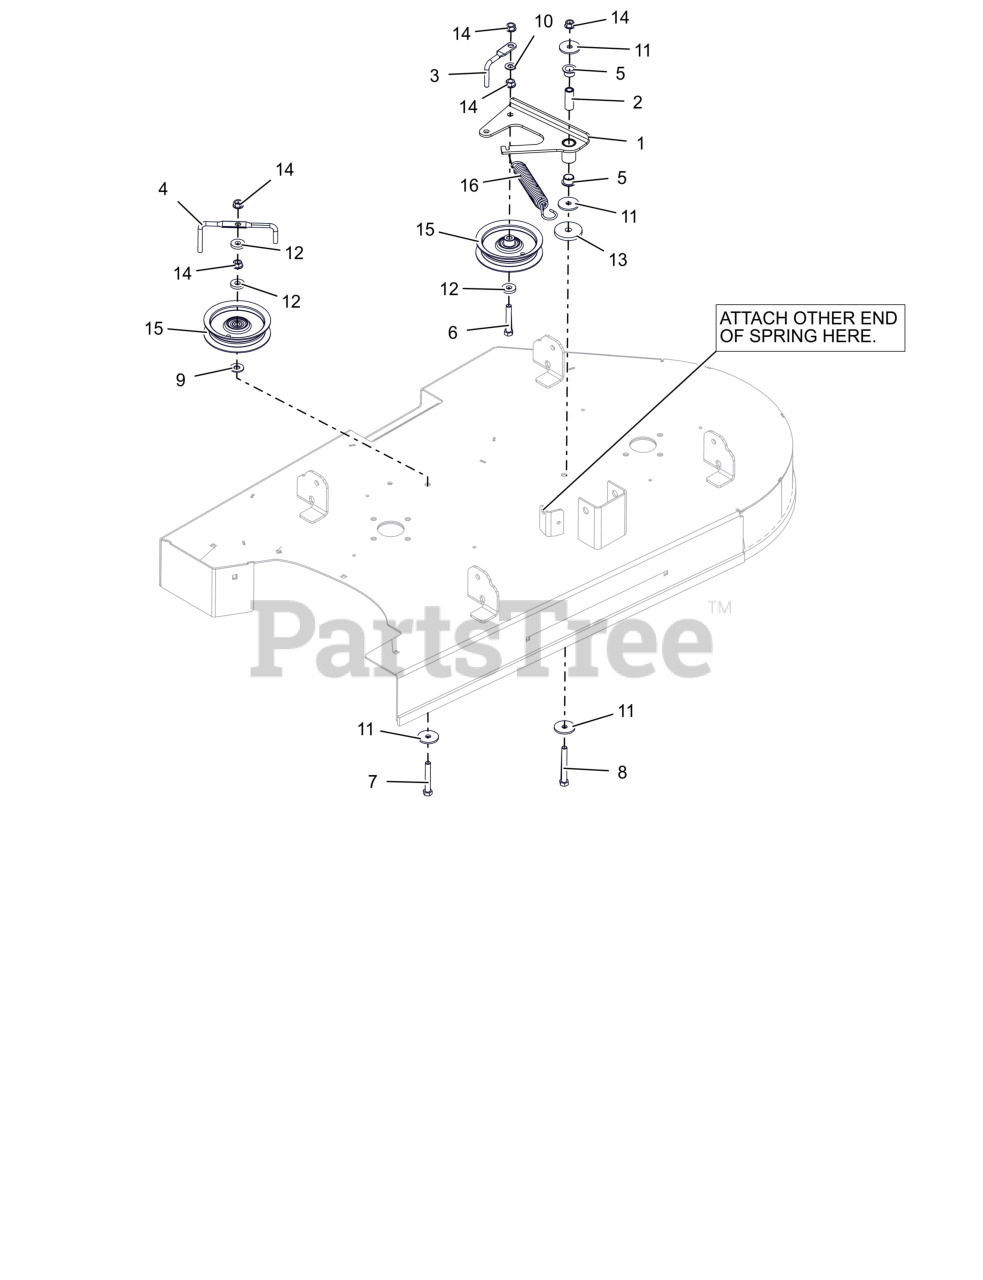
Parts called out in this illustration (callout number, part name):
1	WLDMT, IDLER ARM (ORANGE)
2	SPACER, .375IDX.625ODX1.66 PM
3	WIREFORM-BELT FINGER
4	BELT FINGER
5	BSHG-FLG, .625X.750X.500X1.00
6	BLT,HEX .38-16X2.25 G5 ZCC
7	BLT, HEX .38-16X2.50 G5 ZCC
8	BLT, HEX .38-16X3.00 G5 ZCC
9	WSHR,FLT .438X1.00X.083 ZCC
10	WSHR,FLT .406X.812X.065 ZCC
11	WSHR, FLT .380X1.50X.125 ZCC
12	WSHR, FLT .406X1.00X.188 ZCC
13	WSHR, FLT .469X2.00X.250 ZCC
14	NUT-LK-CTR-FLG .375-16 GF ZCC
15	IDLER, FLAT - 4.06" X .75"
16	SG-TENS .135X.98X6.0 WLD 62
